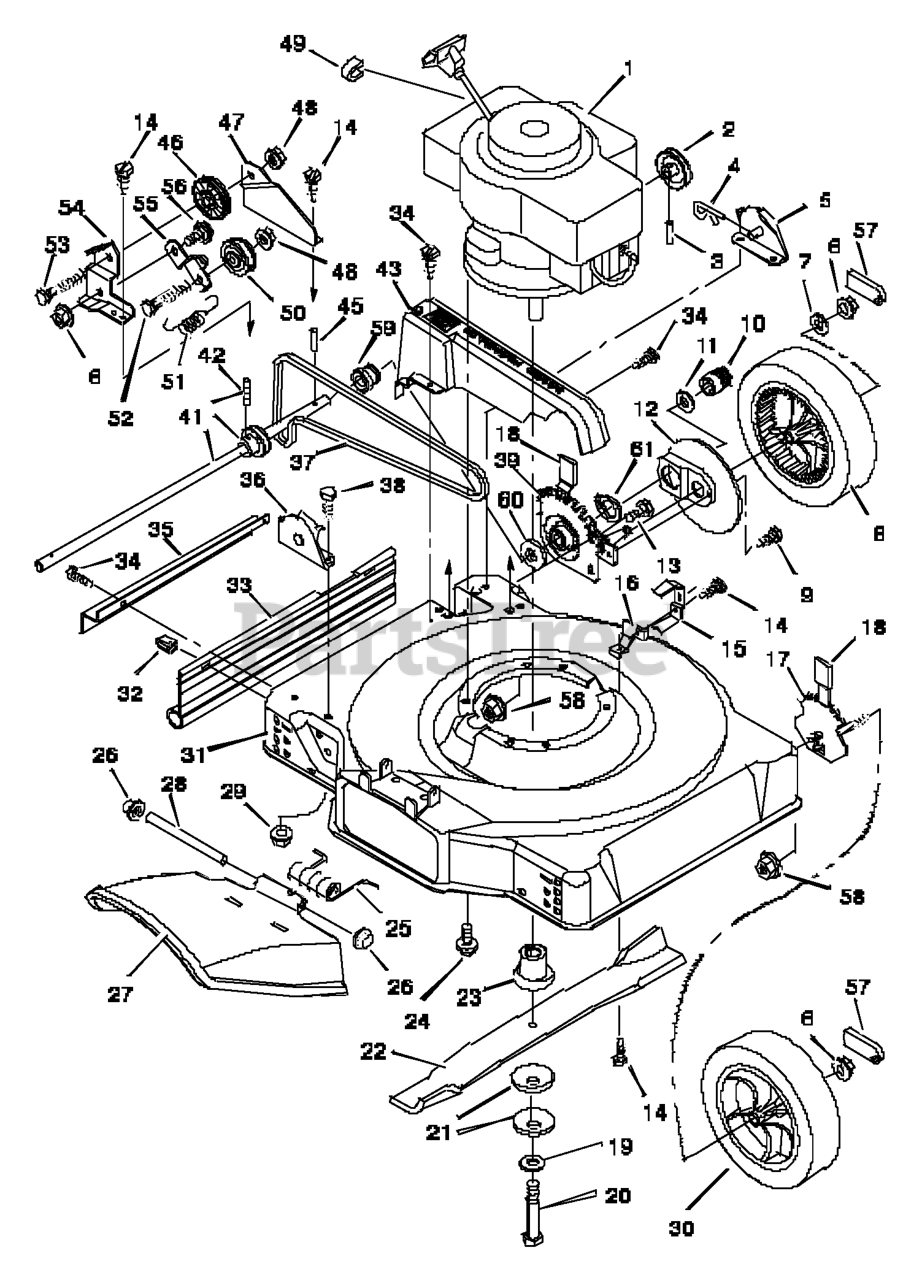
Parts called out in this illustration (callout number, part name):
1	Engine *
3	Pin, Spring
4	Pin, Hair
5	Bracket, Left Handle
6	Nut
7	Washer
8	Wheel, Drive
10	Gear, Right Pinion
12	Cover, Dust
13	Bolt, Hex
15	Guide, Belt
16	Belt Guide, Briggs
17	Height Adjuster, Front
21	Washer, Belleville
23	Adapter, Blade
24	Bolt, Engine
25	Spring, Torsion
26	Push On Cap
27	Deflector, Chute
29	Nut
30	Wheel and Tire, Front
31	Housing
32	Retainer
33	Deflector, Rear
35	Guard, Axle
36	Bracket, Right Handle
37	Belt, Briggs & Stratton
39	Height Adjuster, Left
41	Axle, Pulley & Setscrew
42	Setscrew
43	Belt Guard, Briggs
45	Pin, Drive
46	Pulley, Idler
47	Support, Idler
48	Nut
49	Stop, Rope
50	Pulley, Idler
51	Spring, Extension
52	Bolt, Hex
53	Bolt, Hex
54	Bracket, Idler
55	Arm, Idler
56	Bolt, Shoulder
57	Cap, Hub
58	Nut, Flange
59	Bearing and Retainer
60	Washer, Belleville
61	Retainer Ring
